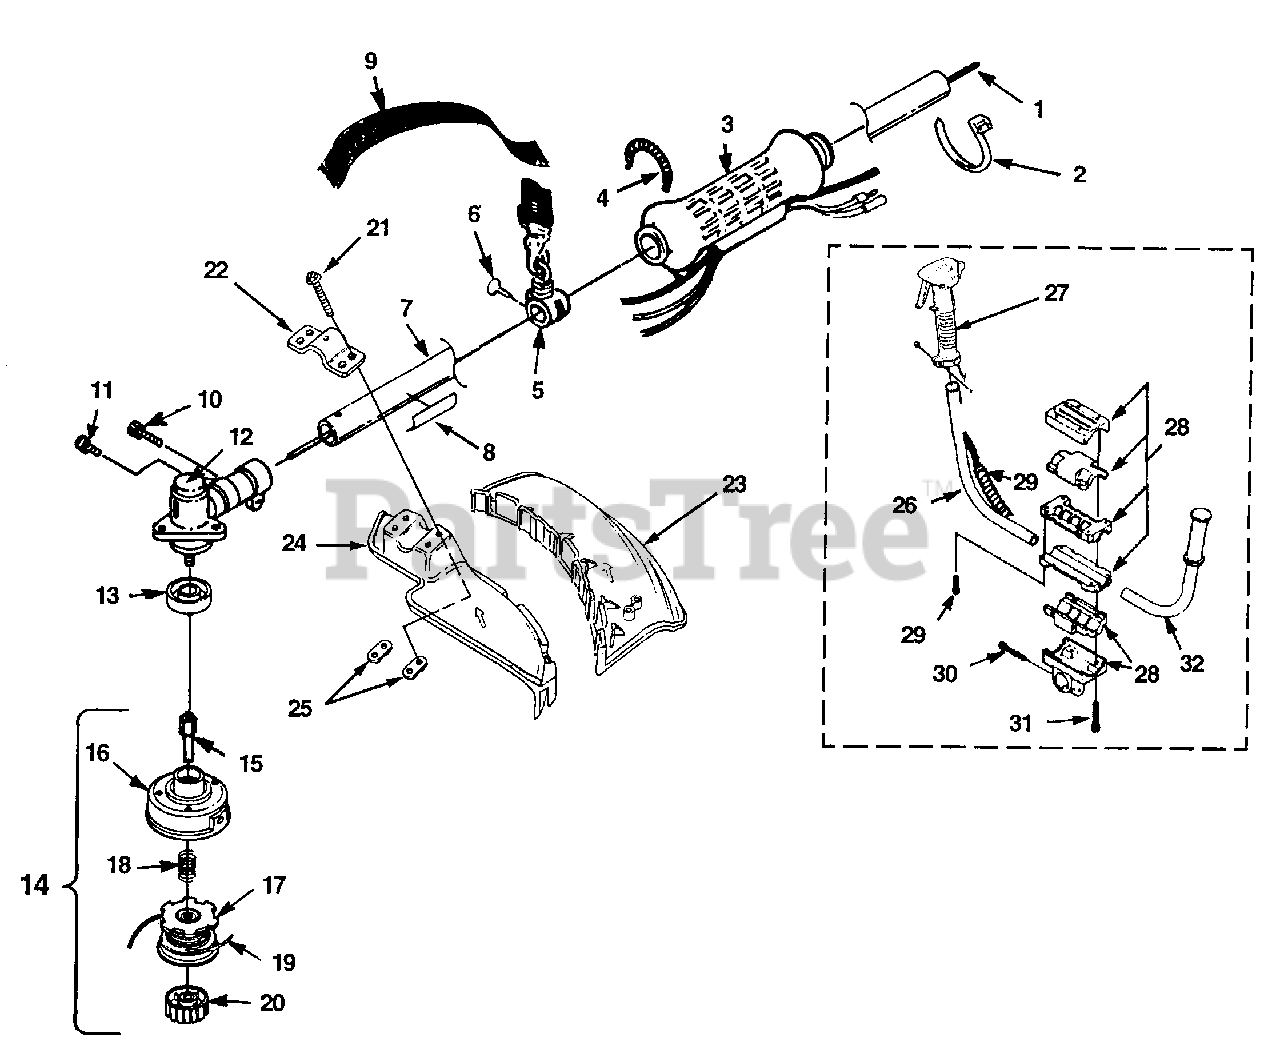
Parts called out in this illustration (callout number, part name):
1	DRIVESHAFT
2	CABLE-Tie
3	GRIP-Handle
4	SPRING-Torsion
5	BRACKET-Hanger
6	SCREW-Thumb (10-24 X 1/2")
7	HOUSING-Driveshaft
8	DECAL-Warning
9	HARNESS w/Connector
10	SCREW-Cap Socket Hd. (10-24 X 1")
11	SCREW-Sems Hex Hd. (10-24 X 1/2")
12	GEAR HEAD
13	WASHER-Flanged
14	STRINGHEAD COMPLETE
15	CONNECTOR-Drive
16	HOUSING & EYELET (Dual Line)
17	SPOOL & STRING (Dual Line)
18	SPRING-Compression
19	LINE-Replacement (.095" Dia.) (285')
20	RETAINER-Spool (L.H.) (Red)
21	SCREW-Mach. Tr. Hd. (10-24 X .750)
22	CLAMP
23	STRING SHIELD
24	BLADE GUARD
25	MOUNTING PLATE
26	HANDLE BAR & CONTROL GRIP
27	BIKE CONTROL GRIP
28	BRACKET-Handle Bar
29	SCREW-Soc. Hd.
30	SCREW-Hex Hd.
31	SCREW-Hex Hd.
32	HANDLE BAR & GRIP
